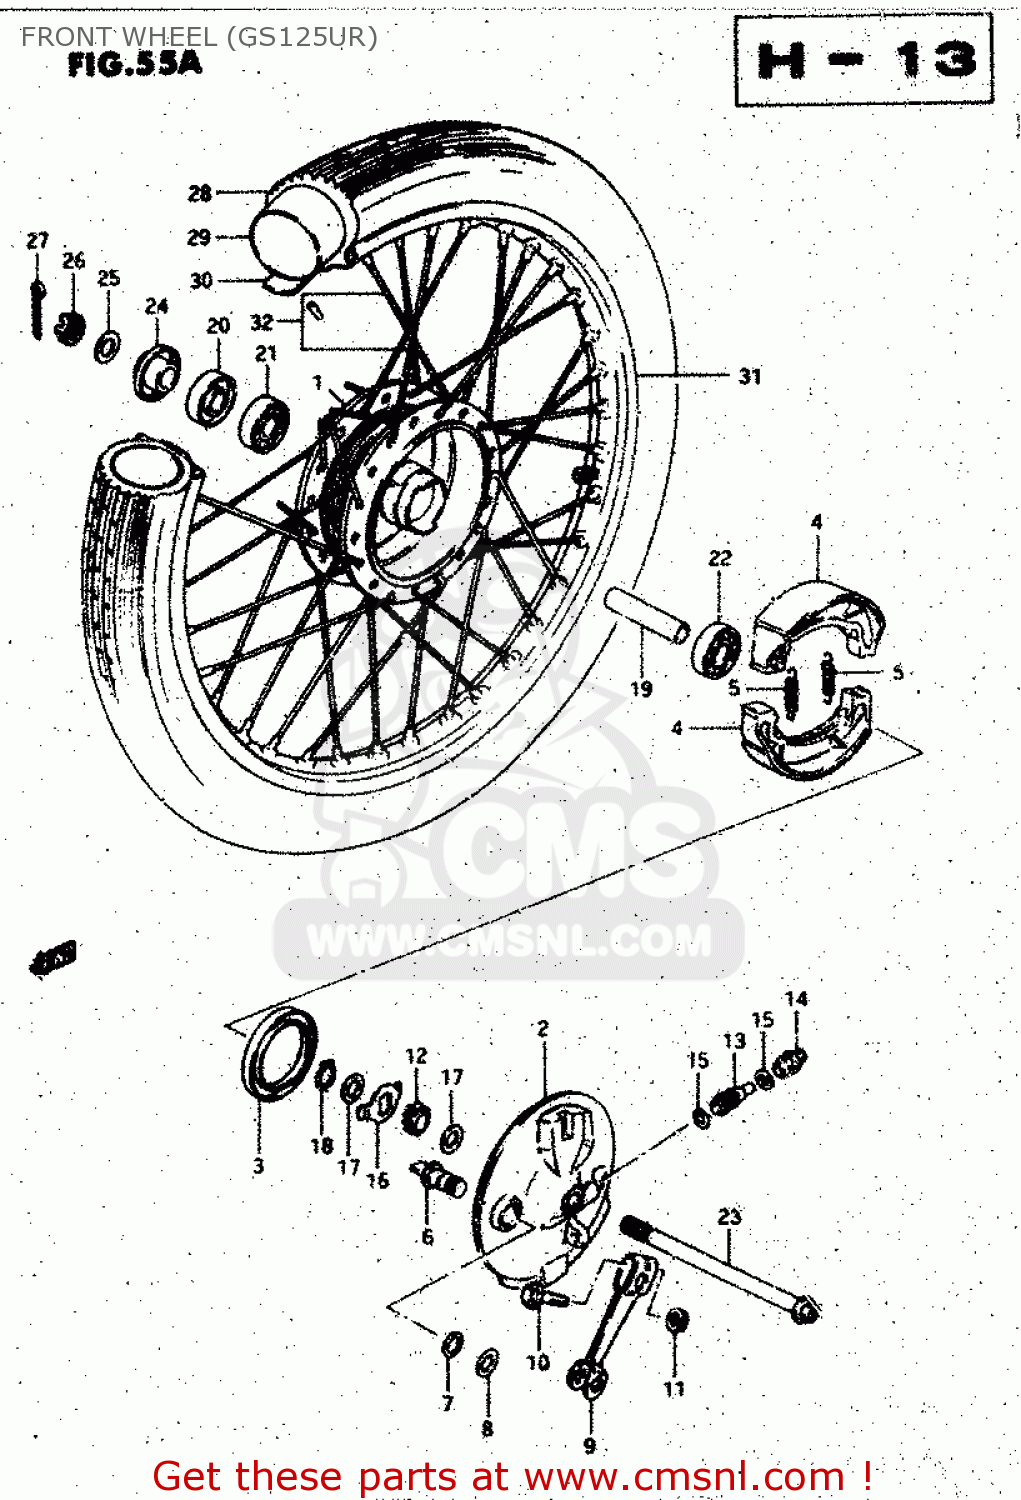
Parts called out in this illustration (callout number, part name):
1	HUB,FR WHEEL
2	PANEL,FRONT BRAKE ANCHOR
3	SEAL,OIL(48X62X7)
4	SHOE,BRAKE
5	SPRING(L:34)
6	CAM,BRAKE
7	O-RING (D:2.4 ID:13.8)
8	WASHER (14.5X22X1.6)
9	LEVER,FR BRAKE CAM
10	BOLT
11	NUT
12	GEAR,SPEEDOMETER(NT:24)
13	PINION,SPEEDOMETER(NT:9)
14	BUSH,SPEEDOMETER PINION OUTER
15	WASHER (5.1X9X0.4)
16	DRIVER,SPEEDOMETER GEAR
17	WASHER(18.5X24X1)
18	CLIP
19	SPACER(12.6X19X47)
20	OIL SEAL(17X38X5)
21	BEARING
22	BEARING
23	AXLE,FR
24	SPACER,FR AXLE,R
25	WASHER
26	NUT
27	COTTER PIN
28	TIRE,FR(2.75-18)
29	TUBE,INNER
30	PROTECTOR,INNER TUBE
31	RIM,FR WHEEL 1.60X18
32	SPOKE SET,FRONT
